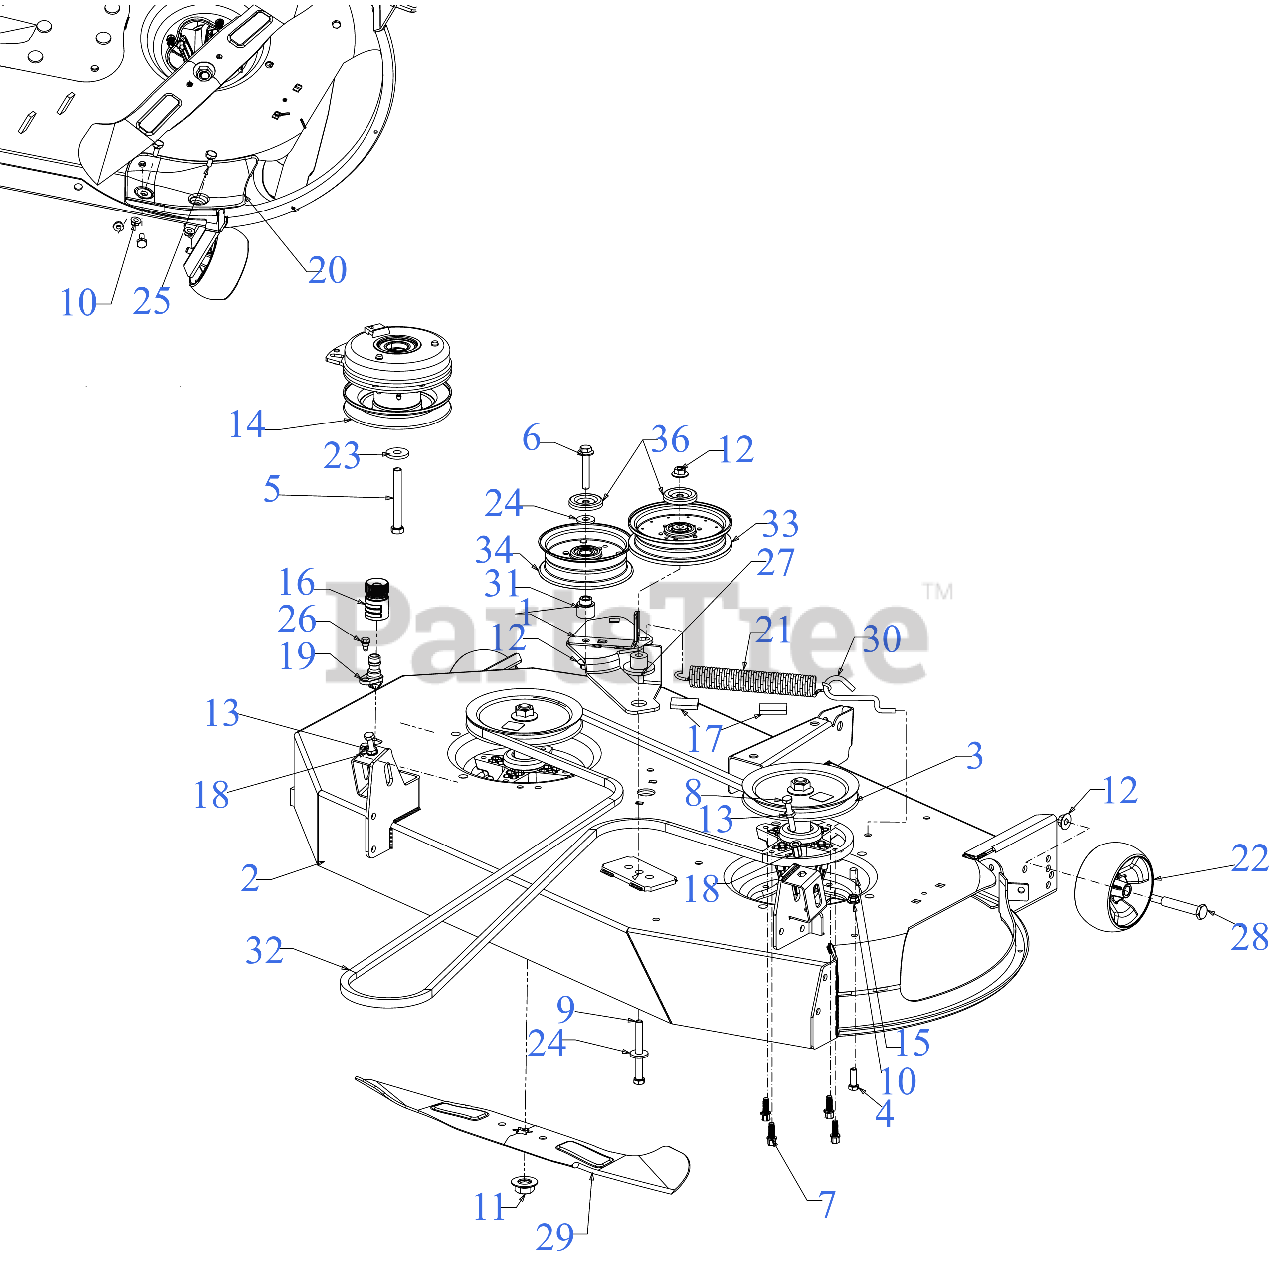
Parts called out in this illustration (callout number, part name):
1	BRACKET ASSEMBLY-DECK IDLER
2	46" FAB DECK SHELL
3	SPINDLE ASSEMBLY
3	Cub Cadet 46" SPINDLE ASSEMBLY (05078A)
4	SCREW 5/16-18 x 1.0 GR5
5	SCREW 7/16-20 x 3.5 GR5
6	SCREW 3/8-16 x 2.25 GR5
7	SCREW 5/16-18 x .875
8	SCREW-FULL THREAD 5/16-18 GR5
9	SCREW 3/8-16 x 3.50 GR5
10	FLANGE LOCK NUT 5/16-18
12	FLANGE LOCK NUT
14	ELECTRIC PTO CLUTCH
16	WATER NOZZLE ADAPTER
17	FOAM TAPE .75" WIDE x .25" THICK
18	NUT RIVET 5/16-18
19	DECK WASH NOZZLE
20	DISCHARGE BAFFLE
21	EXTENSION SPRING
22	DECK WHEEL
22	WHEELS-DELUXE 5"
23	FLAT WASHER .445 x 1.248 x .170
24	FLAT WASHER .406ID X1.0 OD
25	SHOULDER SCREW
26	SHOULDER SCREW 1/4-20 x .50
27	DOUBLE SHOULDER SPACER
28	SHOULDER BOLT .50 x 2.5 x 3/8 -16
29	23.25" BLADE (HIGH LIFT)
29	Cub Cadet 46" BLADE SET
29	Genuine Factory Parts 46" HI LIFT BLADE SET
30	DECK SPRING HOOK
31	SHOULDER SPACER
32	V-BELT A SEC x 120.8
32	Cub Cadet 46" RZT DECK BELT
32	Troy-Bilt 46" RZT DECK BELT
33	FLAT IDLER PULLEY
34	IDLER PULLEY 4.50" DIA
36	IDLER PULLEY CAP
